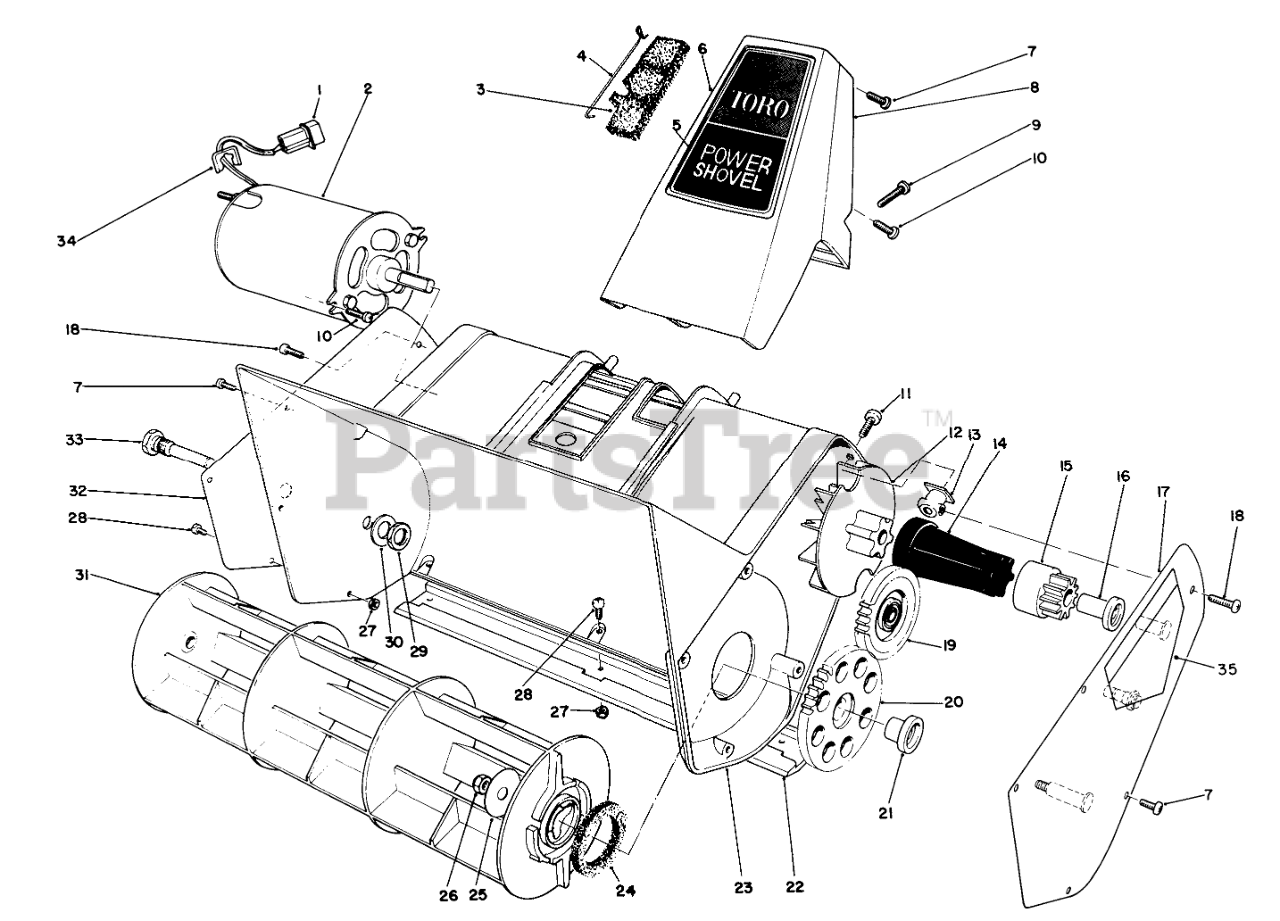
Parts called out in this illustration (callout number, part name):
1	HSG PIN CONNECTOR
2	MOTOR, POWER SHOVEL
3	FOAM FILTER
4	RETAINER - FILTER
5	HANDLE SUPT DECAL
6	HANDLE SUPPORT, FRONT
7	SCREW-PPH
8	Handle Support-Back
9	SCREW-PPH
10	SCREW-PPH
11	#10-10X3/4 PLASCREW
12	FAN, POWER SHOVEL
13	MOUNTING BLOCK
14	DRIVE COUPLING
15	Drive Gear (Incl. Ref. #16)
16	BUSHING, DRIVE GEAR
17	Gear Carrier
18	Screw
19	IDLER GEAR ASM
20	Rotor Gear Assembly (Incl. Ref. #21)
21	BUSHING, ROTOR GEAR
22	Scraper
23	H.S. HOUSING-CSA
24	FELT WASHER
25	ROTOR WASHER
26	NUT-LOCK, NI
27	NUT-LOCK
28	SCREW-PPH
29	NUT-LOCK, CONE
30	WASHER-FLAT
31	ROTOR
32	Cover-Right Side
33	ROTOR PIN
34	Strain Relief
35	DECAL-DANGER
